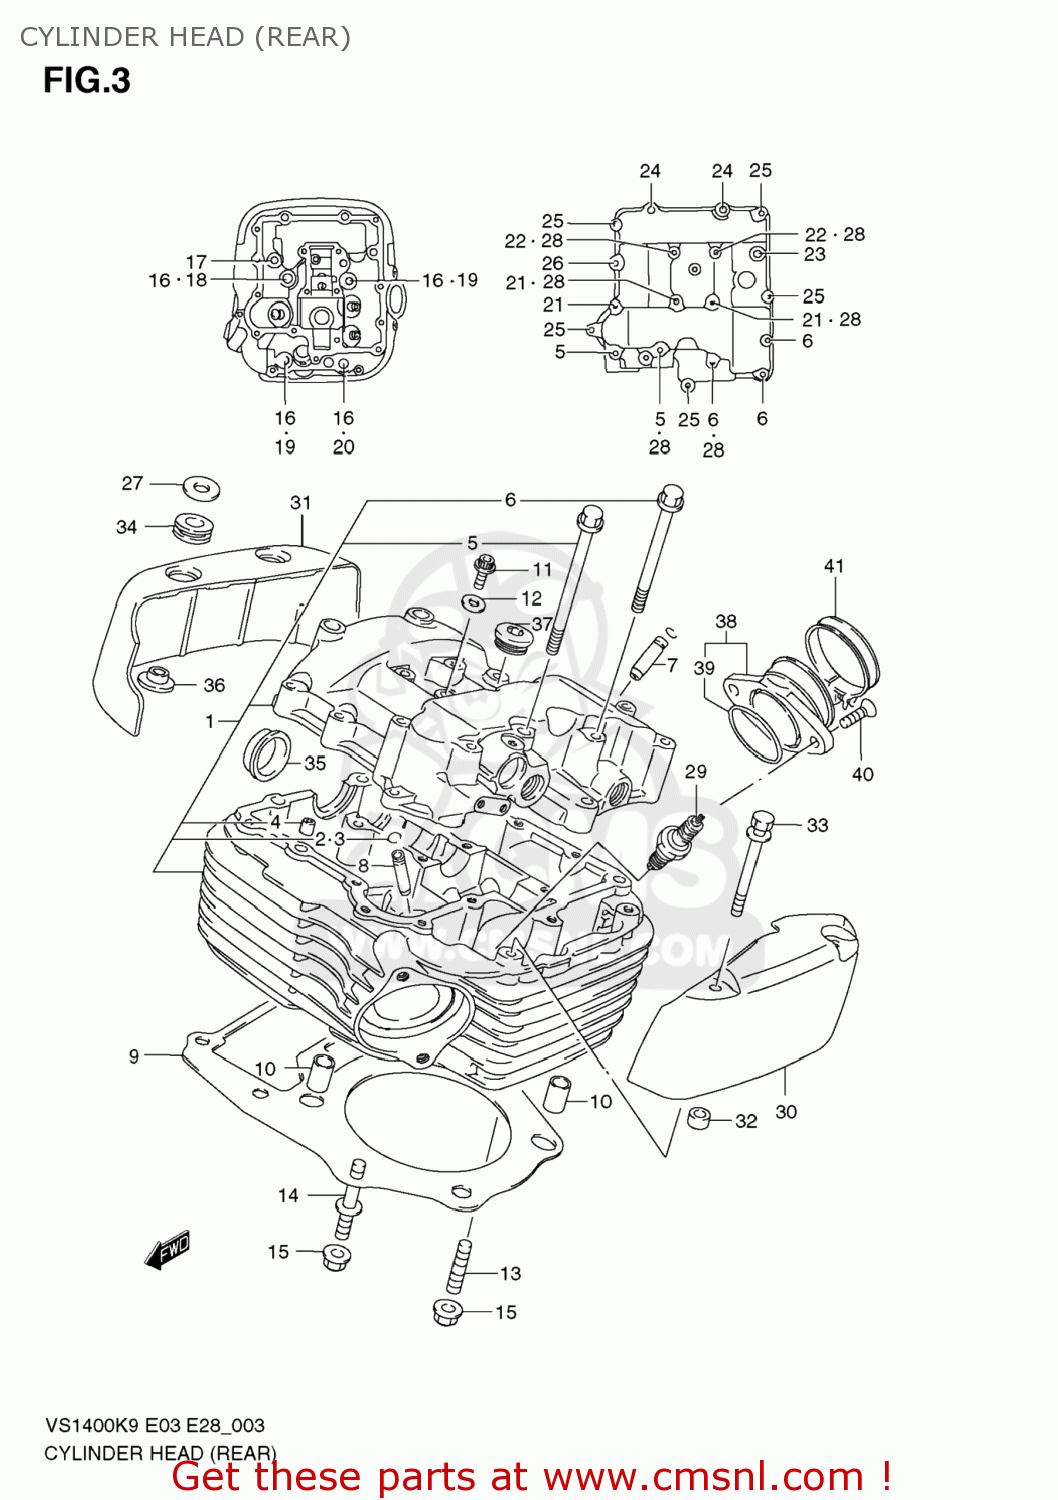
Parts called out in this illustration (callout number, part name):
1	HEAD ASSY,CYLINDER RR
2	RING,SNAP
3	RING,SNAP
4	PIN(6.2X8X11)
5	BOLT(6X60)
6	BOLT(6X55)
7	GUIDE,INTAKE VALVE
8	GUIDE,INTAKE VALVE
9	GASKET,CYLINDER HEAD RR (NAS)
10	PIN
11	BOLT
12	GASKET(6.2X13X1.2) (NAS)
13	BOLT,STUD
14	BOLT,STUD
15	NUT
16	WASHER(10.5X22X2.3)
17	BOLT(8X57)
18	BOLT(10X180)
19	BOLT(10X190)
20	BOLT(10X215)
21	BOLT(6X50)
22	BOLT(6X45)
23	BOLT(8X130)
24	BOLT(8X268)
25	BOLT
26	BOLT
27	WASHER(8.5X24X1.6)
28	GASKET(5.8X13X1.2) (NAS)
29	SPARK PLUG X22E
30	CAP,CYLINDER HEAD COVER RL
31	CAP,CYLINDER HEAD COVER RR
32	CUSHION,R CAP
33	BOLT
34	CUSHION
35	PLUG(OD:30)
36	BUSH
37	PLUG,22X11
38	PIPE ASSY,INTAKE RR
39	O RING(D:1.9,ID:40.7)
40	SCREW
41	CLAMP
